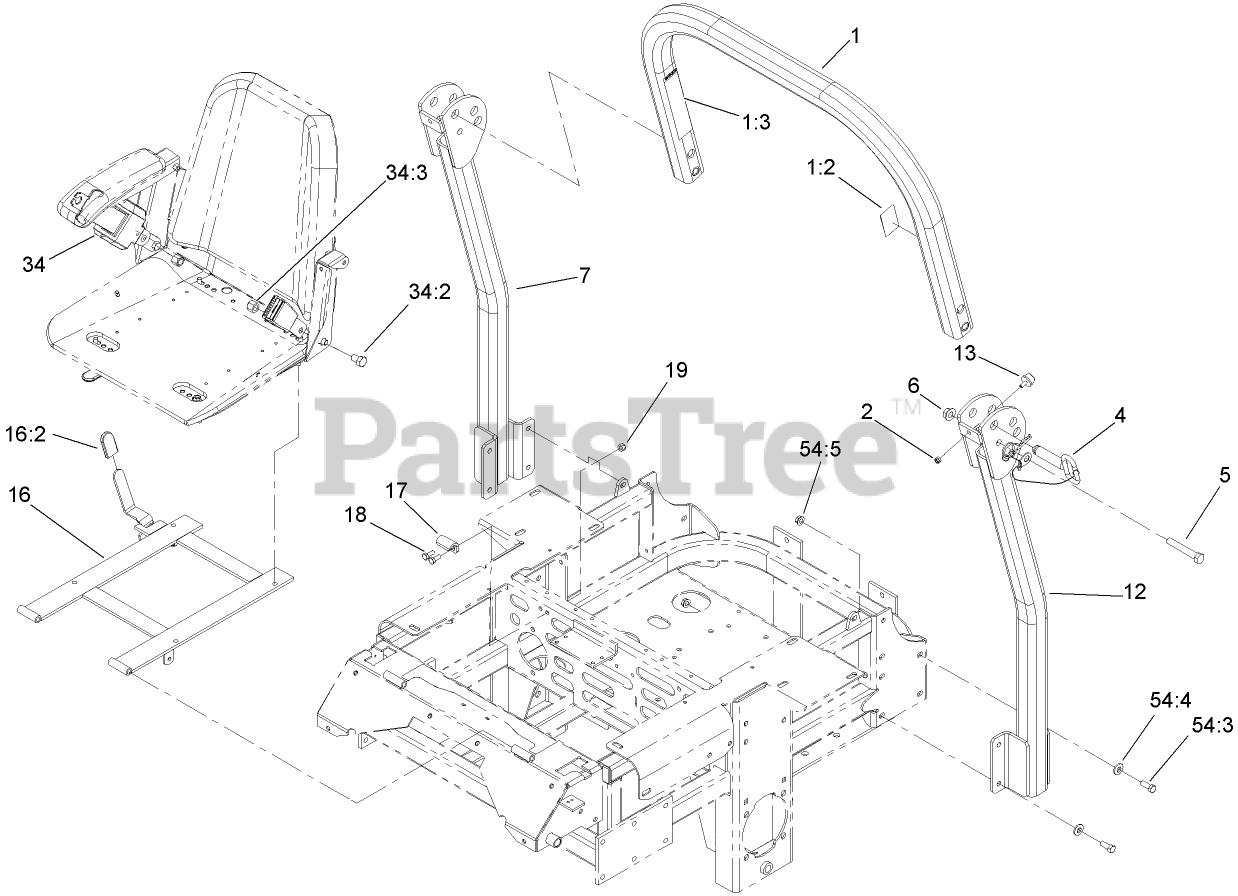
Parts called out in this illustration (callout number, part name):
1	Upper Tube ASM
1:2	DECAL-ROPS
1:3	DECAL-WARNING, FOLDING ROPS
2	NUT-LOCK, NI
4	PIN-FOLD, ROPS
5	SCREW-HH
6	NUT-HF
7	TUBE-SUPPORT, RH
12	TUBE-SUPPORT, LH
13	BUMPER-RUBBER
16	SEAT FRAME AND LATCH ASM
16:2	GRIP-LEVER
17	Catch-Latch, Seat
18	SCREW-HH
19	NUT-LOCK, NI
34	RETRACTABLE SEATBELT KIT
34:2	SCREW-HH
34:3	NUT-LOCK
54	ROPS BOLT PACKAGE ASM
54:3	SCREW-HH
54:4	WASHER-BELLEVILLE
54:5	NUT-HHF, WHIZ
